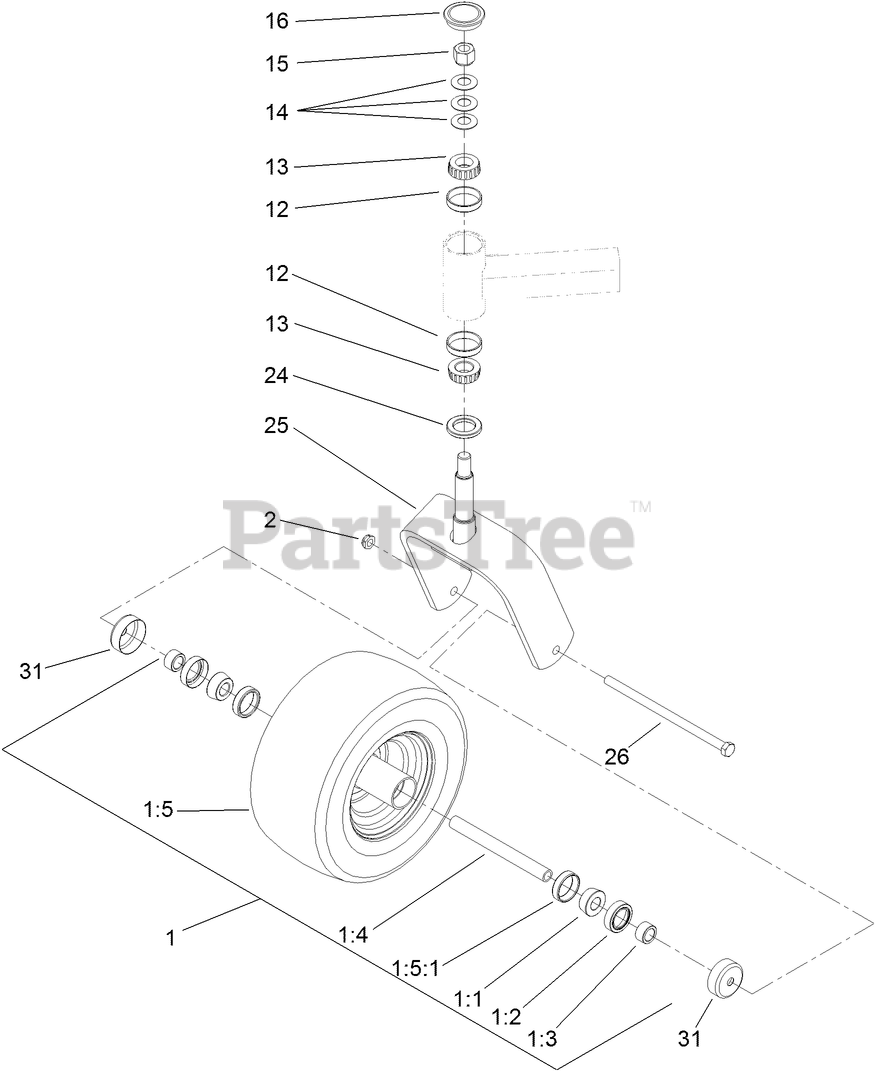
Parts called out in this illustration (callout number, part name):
1	WHEEL AND BEARING ASM
1:1	BEARING-CONE, TAPER
1:2	SEAL-CASTER
1:3	SPACER-NUT
1:4	AXLE CASTER ASM
1:5	Deck ASM
1:5:1	BEARING-CUP
2	NUT-HEX
12	BEARING-CUP, TAPERED
13	BEARING-CONE, TAPERED
14	WASHER-BELLVILLE
15	NUT-LOCK, NI
16	CAP-GREASE
24	SEAL-GREASE
26	SCREW-HH
31	GUARD-SEAL
